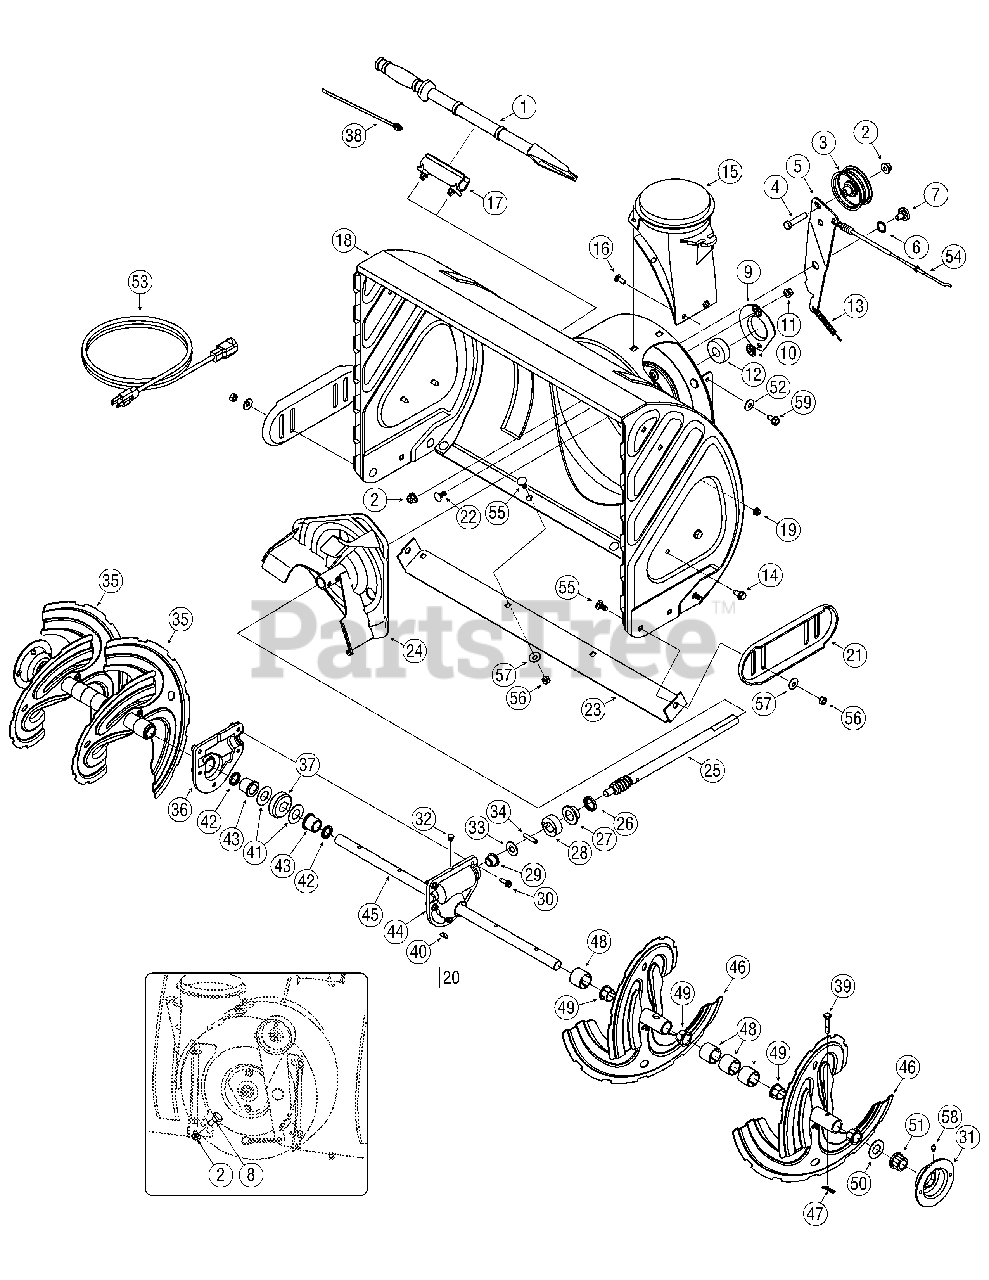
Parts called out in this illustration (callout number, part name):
1	Clean-Out Tool
2	Flange Lock Nut
3	Flat Idler Pulley
4	Hex Bolt, 3/8-16 x 1.75
6	Wave Washer
7	Shoulder Screw
8	Shoulder Screw
9	Bearing Housing
11	Flange Lock Nut, 5/16-18
12	Ball Bearing
13	Extension Spring
14	AB Screw, 5/16-18 x 0.625
15	Chute Adapter
16	Carriage Screw, 1/4-20 x 0.75
17	Clean-out Tool Mtg. Bracket
19	Flange Lock Nut, 1/4-20
20	Gearbox Assembly Complete
21	Slide Shoe, Stainless
22	Carriage Bolt
23	Shave Plate
25	Worm Shaft
27	Flange Bearing
28	Thrust Collar
29	Flange Bearing
30	TT Screw, 1/4-20 x 0.75
33	Flat Washer
36	Reducer Hsg.-RH (Incl Ref. 44-45)
37	Worm Gear, 20T
38	Cable Tie
40	Key
41	Flat Washer
43	Flange Bearing
44	Reducer Hsg.- LH (Incl Ref. 44-45)
45	Auger Axle 28-inch
47	Bow Tie Cotter Pin
49	Flange Bushing
50	Flat Washer
51	Hex Flange Bearing
52	Bell Washer
53	Extension Cord
54	Auger Clutch Cable
55	Carriage Bolt, 5/16-18 x .750
56	Hex Nut, 5/16-18
57	Bell Washer, .340 x .872 x .060
58	Drive Lube Fitting
59	AB Screw, 5/16-18 x 0.75
